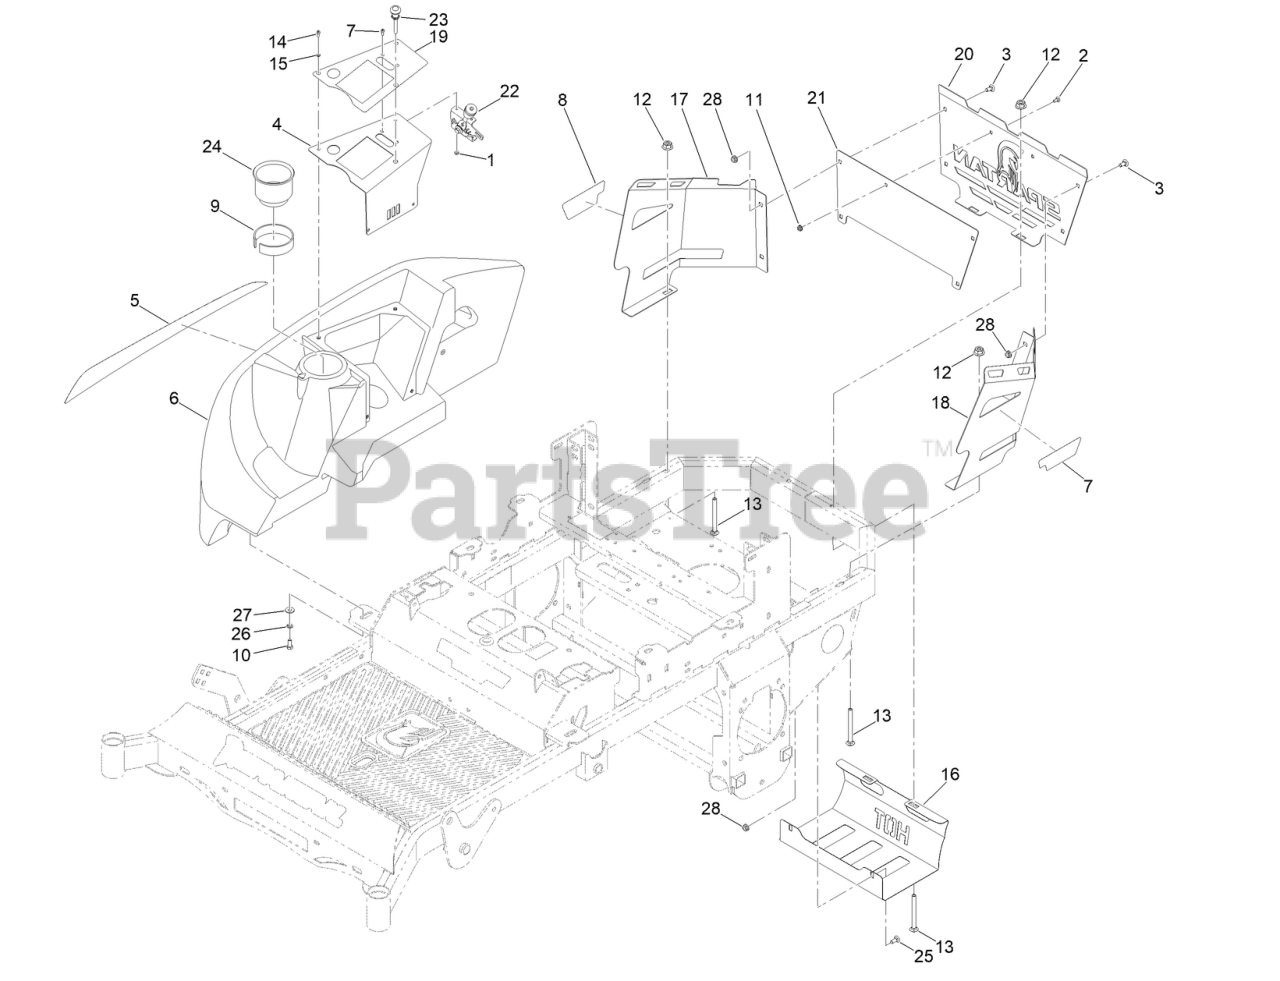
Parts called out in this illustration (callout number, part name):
1	NUT-LOCK
2	SCREW-CARR
3	BOLT-CARR
4	BRKT-CONTROL PANEL
5	DECAL-POD RH
6	CONSOLE W/ CUPHOLDER
7	DECAL- RZ HD BLACKOUT MODEL
8	DECAL- RZ HD BLACKOUT MODEL
9	TAPE-FOAM
10	SCREW-HH
11	1/4-20 HEX FLANGE NUT
12	3/8-16 NYLON INSERT FLANGE L/NUT YZ
13	3/8-16 X 4 CARRIAGE BOLT ZINC
14	10-24 X 1/2 SOCKET C/S 18-8 SS
15	#10 SPLIT LOCKWASHER 18-8 SS
16	RZ MWR MUFFLER GUARD PAINTED BLACK
17	ENGN COWLING RT SIDE RT TANK UPGR
18	RZ ENGN COWLNG LT SIDE RT TANK UPGR
19	DECAL-CONSOLE
20	PLATE - ENGINE COWLING
21	PLATE -BACKER PLATE
22	MWR THROTTLE CABLE ASSY W / HANDLE
23	MWR CHOKE CABLE ASSM
24	CUP HOLDER
25	BOLT-CARR
26	WASHER-LOCK
27	WASHER-FLAT
